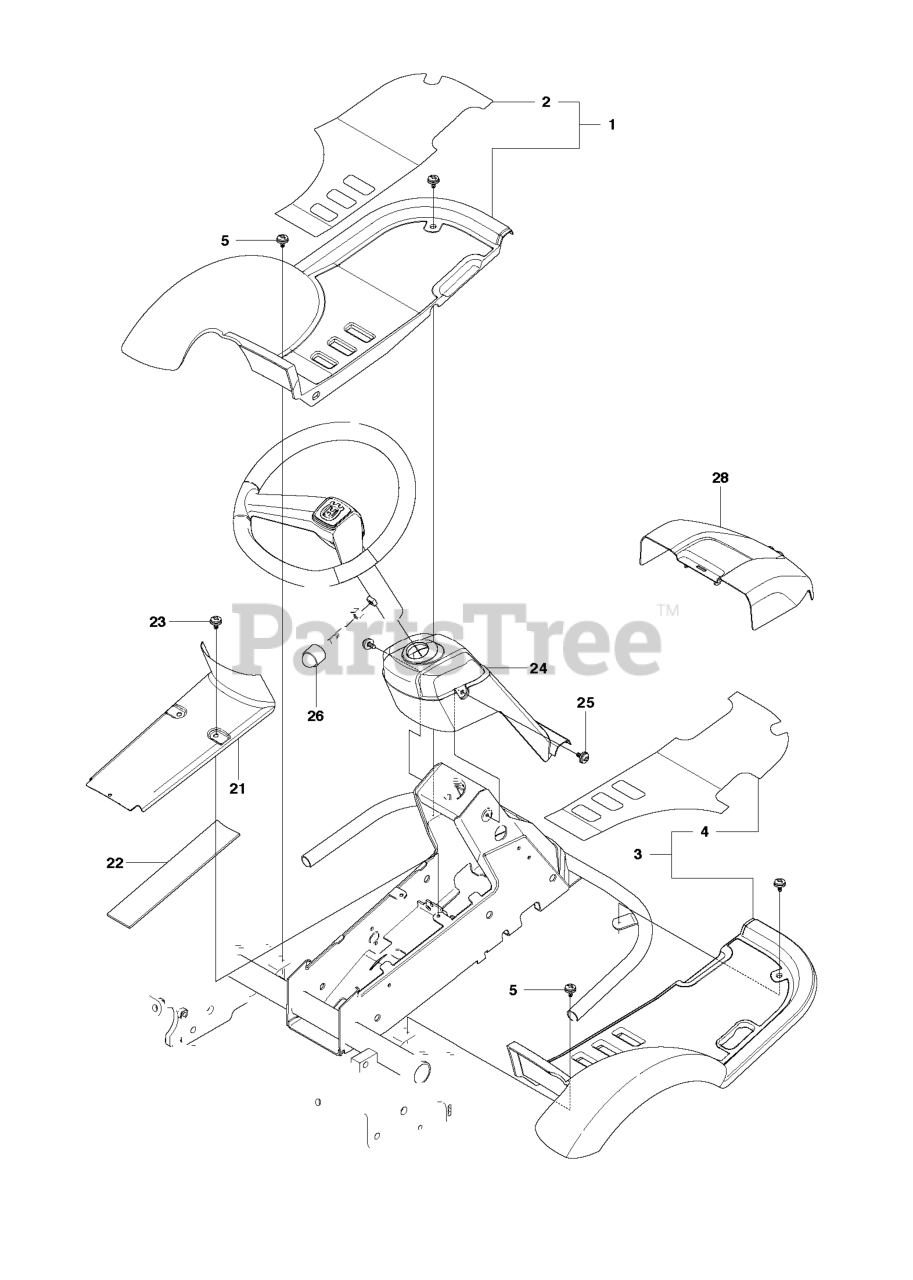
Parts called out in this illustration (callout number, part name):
1	FOOT PLATE
3	FOOT PLATE
26	PROTECTIVE COVER
28	UNIT COVER
